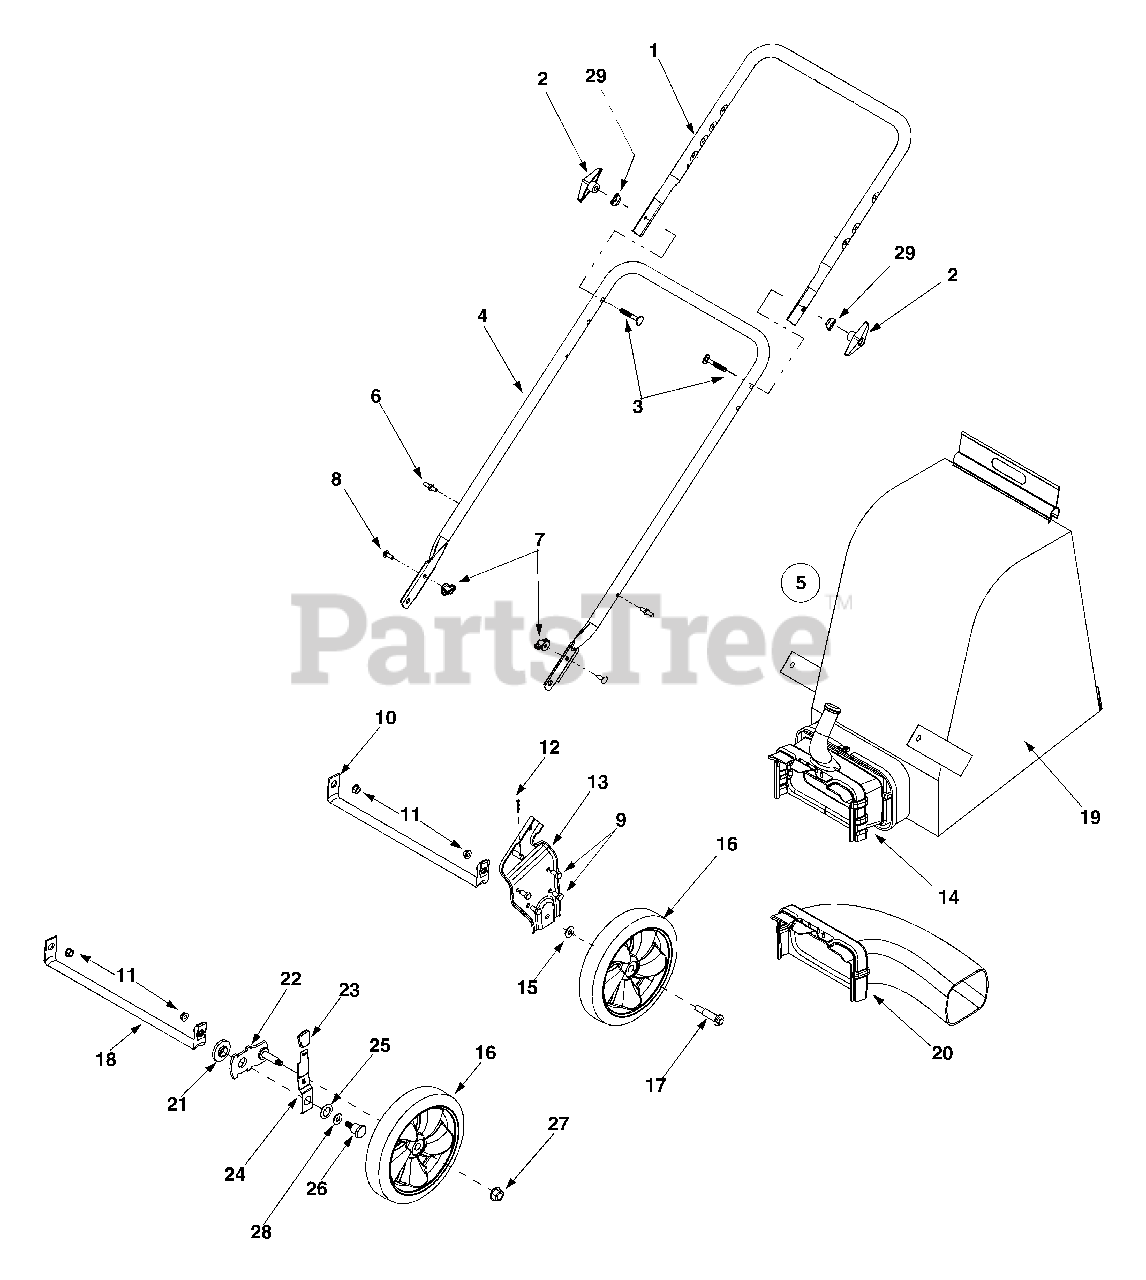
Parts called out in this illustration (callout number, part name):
2	Handle Knob 5/16-18
3	Carriage Bolt
5	Bag Assembly
6	Studs
7	Wing Nut 1/4-20
8	Carriage Screw 1/4-20 x.75
9	Hex Cap Screw 5/16-12 x.750
11	Flange Lock Nut, 3/8-16
12	Cotter Pin
14	Chute Assembly
15	Bell Washer.401 ID x.870 OD
16	Wheel 8 x 8.1
17	Shoulder Screw 3/8-16
19	Bag
20	Blower Chute Ass'y
21	Height Adjustment Bearing
22	Pivot Arm Assembly
23	Height Adjustment Knob
24	Spring Lever
25	Bell Washer.760 ID x.25OD
26	Shoulder Screw,.750 x.500
27	Flange Lock Nut 3/8-16
28	Thrust Washer.375 x.70 x.030
29	Saddle Washer
